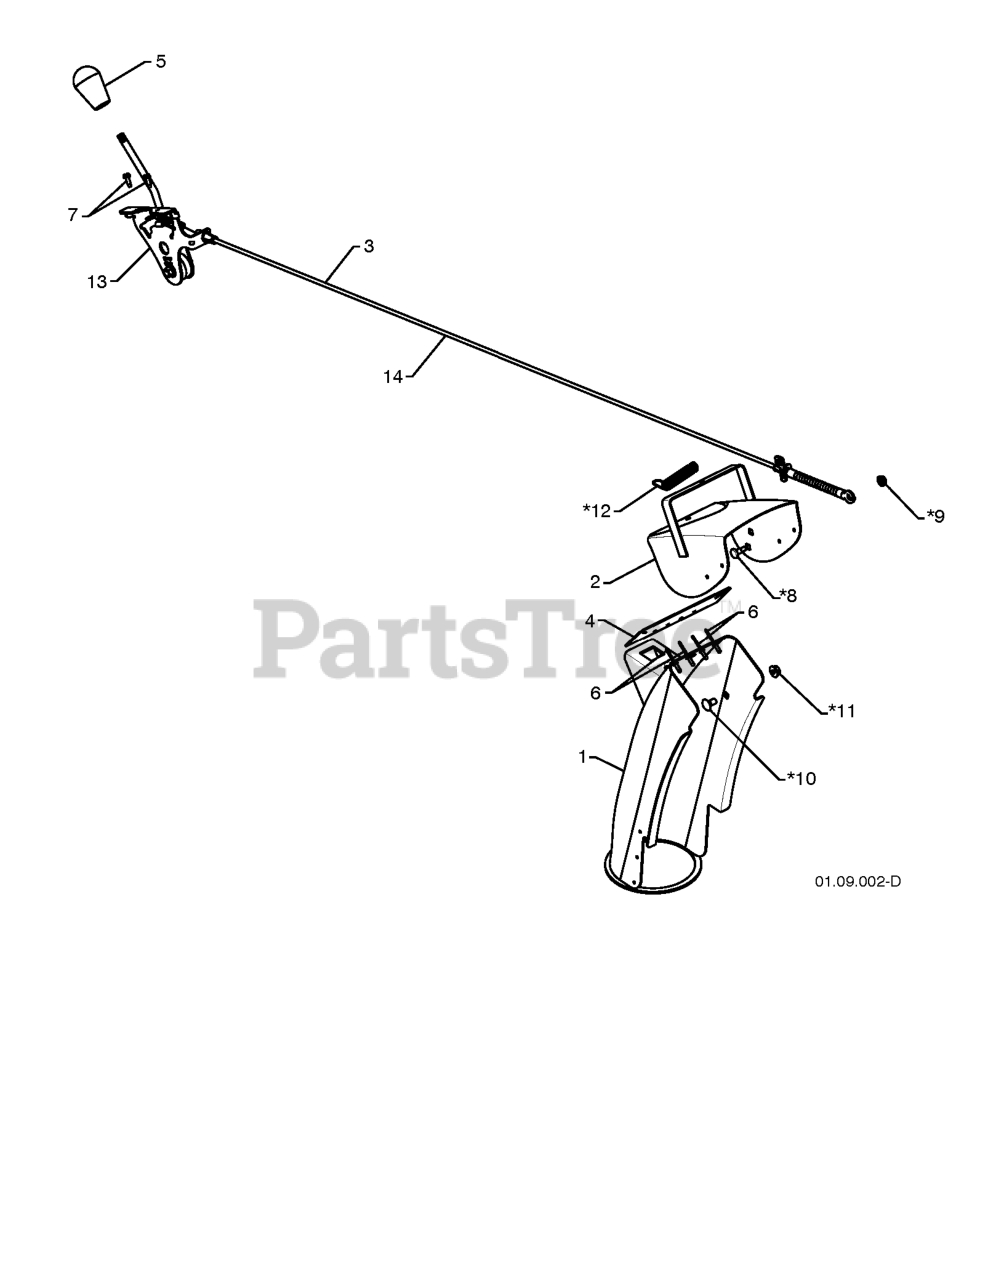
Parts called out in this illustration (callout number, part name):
1	CHUTE.WELDMENT
2	DEFLECTOR.WELDMENT.PNT.ORANGE
3	RP.CONTROL.ASM.DEFLECTOR.SNOW
4	SEAL.DEFLECTOR
5	KNOB LEVER, BLACK
6	RIVET BLIND
7	SCREW #10-24 X 5/8
8	BOLT, SHOULDER
9	NUT.HEX.FLANGE.1/4
10	BOLT
11	NUT.LOCK.5/16-18
12	SPRING.DEFLECTOR.REM.CHUTE
13	RP CNTRL.HEAD.ASSEM.DEFLECTOR
14	RB SERVICE.CHUTE.DEF.CBL.BLK
